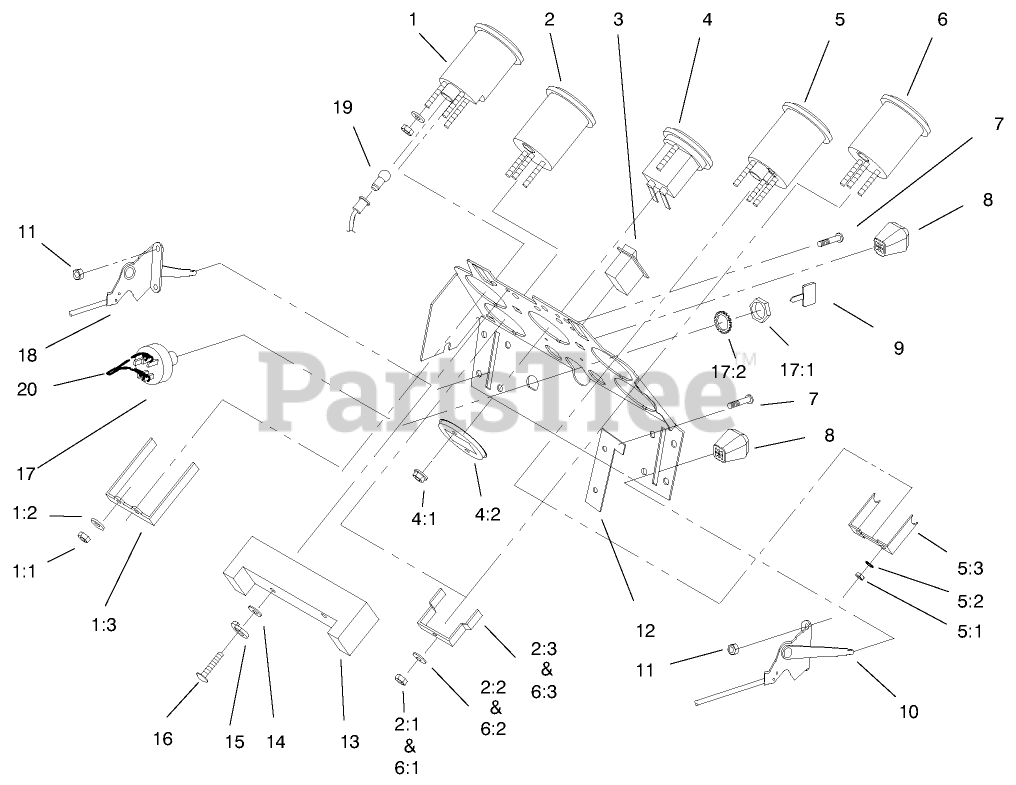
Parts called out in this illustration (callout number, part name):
1	TACHOMETER
1:1	NUT-HEX
1:3	BRACKET - GAUGE MOUNT
2:1	NUT-HEX
2:3	CLAMP-MOUNTING
4:1	NUT-HEX, KEPS
4:2	Retainer
5:1	NUT-HEX
5:3	Bracket-Mounting
6:1	NUT-HEX
6:3	CLAMP-MOUNTING
7	SCREW-PPH
9	KEY-IGNITION
10	CONTROL-CHOKE
12	Stop-Choke
14	WASHER-FLAT
15	WASHER-LOCK
16	Screw
17:2	WASHER-LOCK
18	CONTROL-THROTTLE
